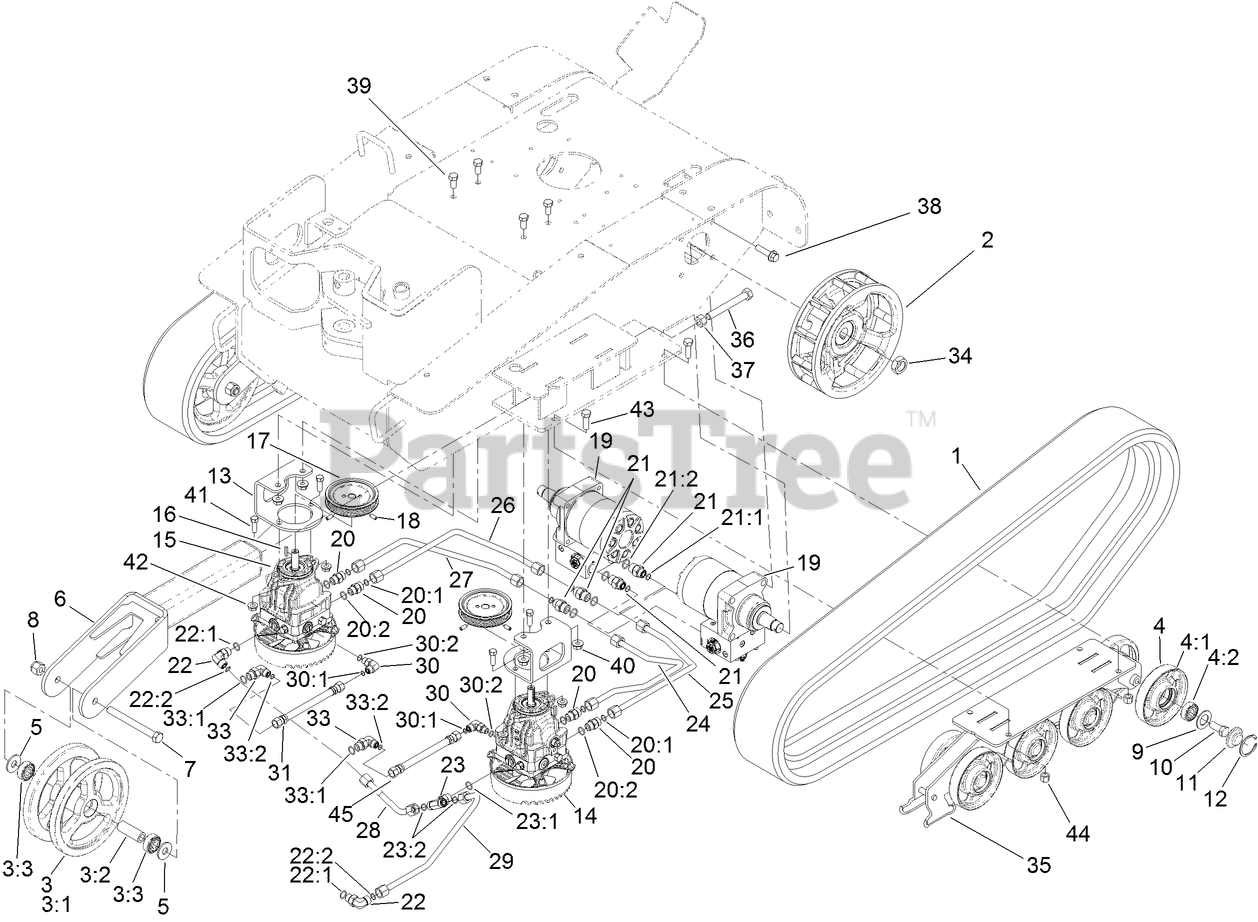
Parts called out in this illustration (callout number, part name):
1	TRACK-RUBBER
2	WHEEL-DRIVE
3	TENSIONER WHEEL ASM
3:1	WHEEL-TENSIONER
3:2	SPACER-WHEEL, TENSIONER
3:3	BEARING-BALL
4	WHEEL-TENSIONER
4:1	WHEEL-TRACK
4:2	BEARING-BALL
5	WASHER-FLAT
6	ARM-TENSIONER
7	SCREW-HH
8	NUT-HEX
9	Gasket-Bogie
10	SCREW-HH
11	CAP-WHEEL, BEARING
12	RING-SNAP, INTERNAL
13	BRACKET-MOUNT, PUMP
14	PUMP-HYD, LH
15	PUMP-HYD, RH
16	KEY-PUMP
17	Sheave
18	SCREW-SET, HSH
19	HYD MOTOR ASM
20	FITTING-STRAIGHT
20:1	O-RING
20:2	O-RING
21	FITTING-STRAIGHT
21:1	O-RING
21:2	O-RING
22	FITTING-ELBOW-90 DEG
22:1	O-RING
22:2	O-RING
23	FITTING-HYD, TEE
23:1	O-RING
23:2	O-RING
24	TUBE-HYD
25	TUBE-HYD
26	TUBE-HYD
27	TUBE-HYD
28	TUBE-HYD
29	TUBE-HYD
30	FITTING-ELBOW, 90 DEG
30:1	O-RING
30:2	O-RING
31	HOSE-HYD
33	FITTING-HYD, 90 DEG
33:1	O-RING
33:2	O-RING
34	NUT-LOCK
35	MOUNT-WHEEL
36	SCREW-HH, TAP
37	NUT-HEX
38	SCREW-HHF
39	SCREW-HH
40	NUT-HHF
41	SCREW-HH
42	NUT-HF
43	SCREW-HH
44	NUT-LOCK, NI
45	HOSE-HYD
